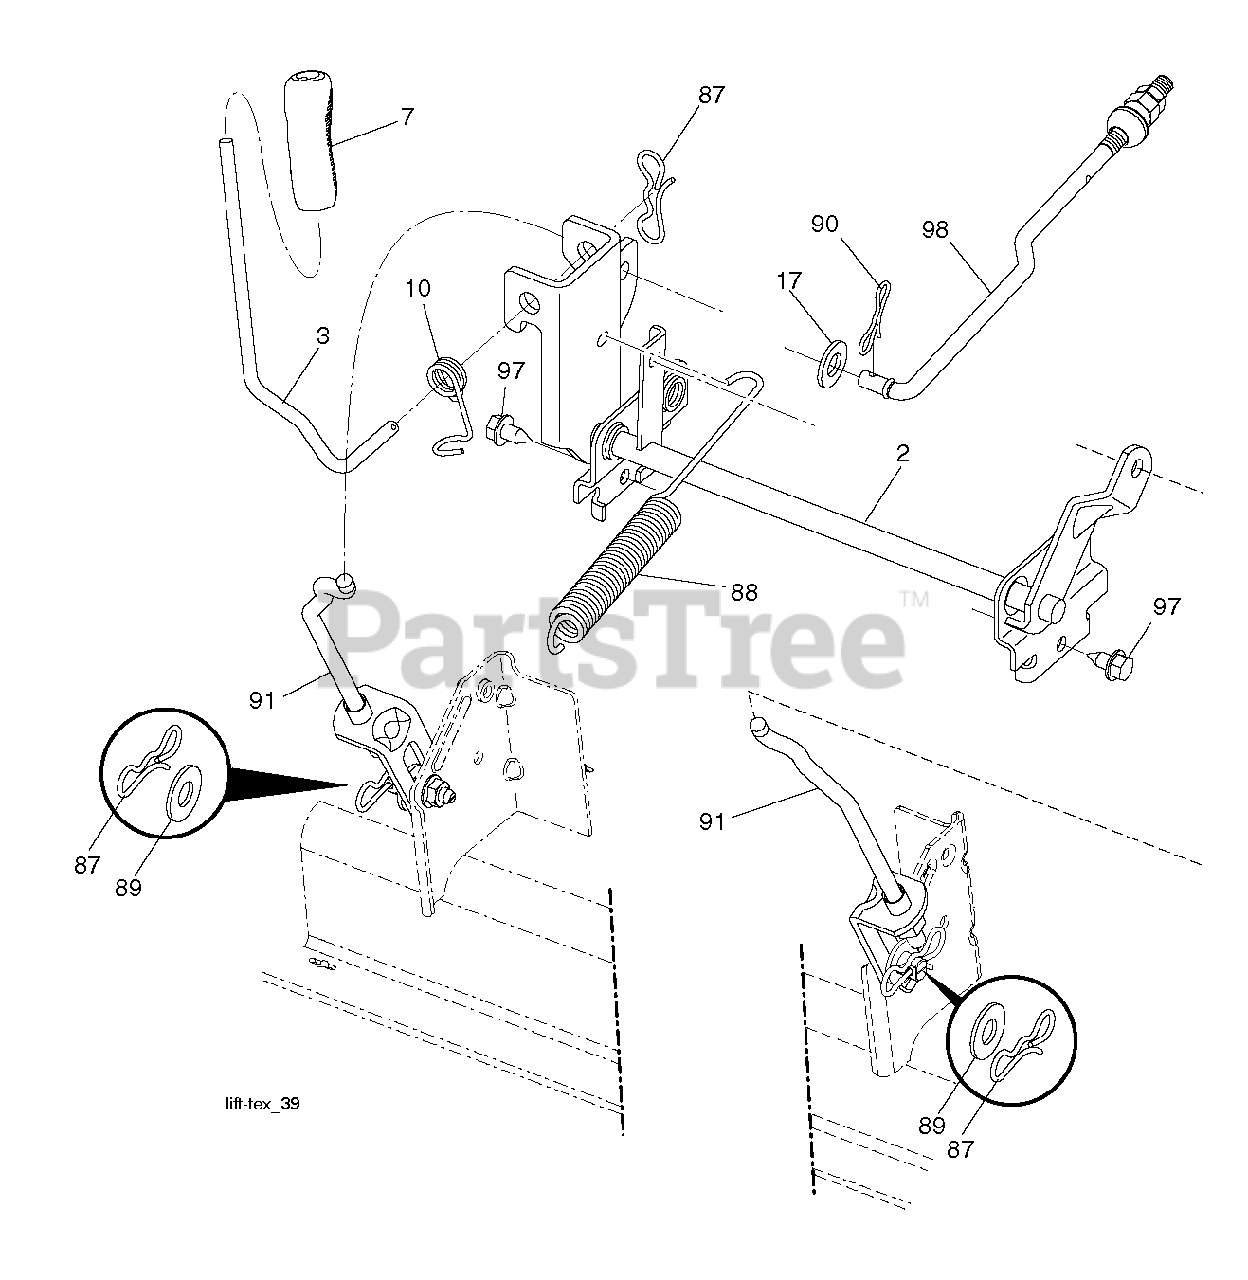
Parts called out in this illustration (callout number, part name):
2	SHAFT.ASM.CROSS.LIFT
3	LEVER.LIFT.HANDLE.LT
7	GRIP.HANDLE.LIFT.PVC.BLACK
10	SPRING.TORSION.LIFT.HANDLE
17	WASHER
87	PIN.COTTER.7/16.BOW TI.
88	SPRING.LIFT.ASSIST
89	WASHER.CLEAR.ZINC
90	PIN.COTTER.5/16.BOW TI
91	LINK.LIFT.ASM.REAR.GT.
97	SCREW, 3/8-16X3/4
98	LINK.FRONT.MOWER.SUSP.ASM.BLK
